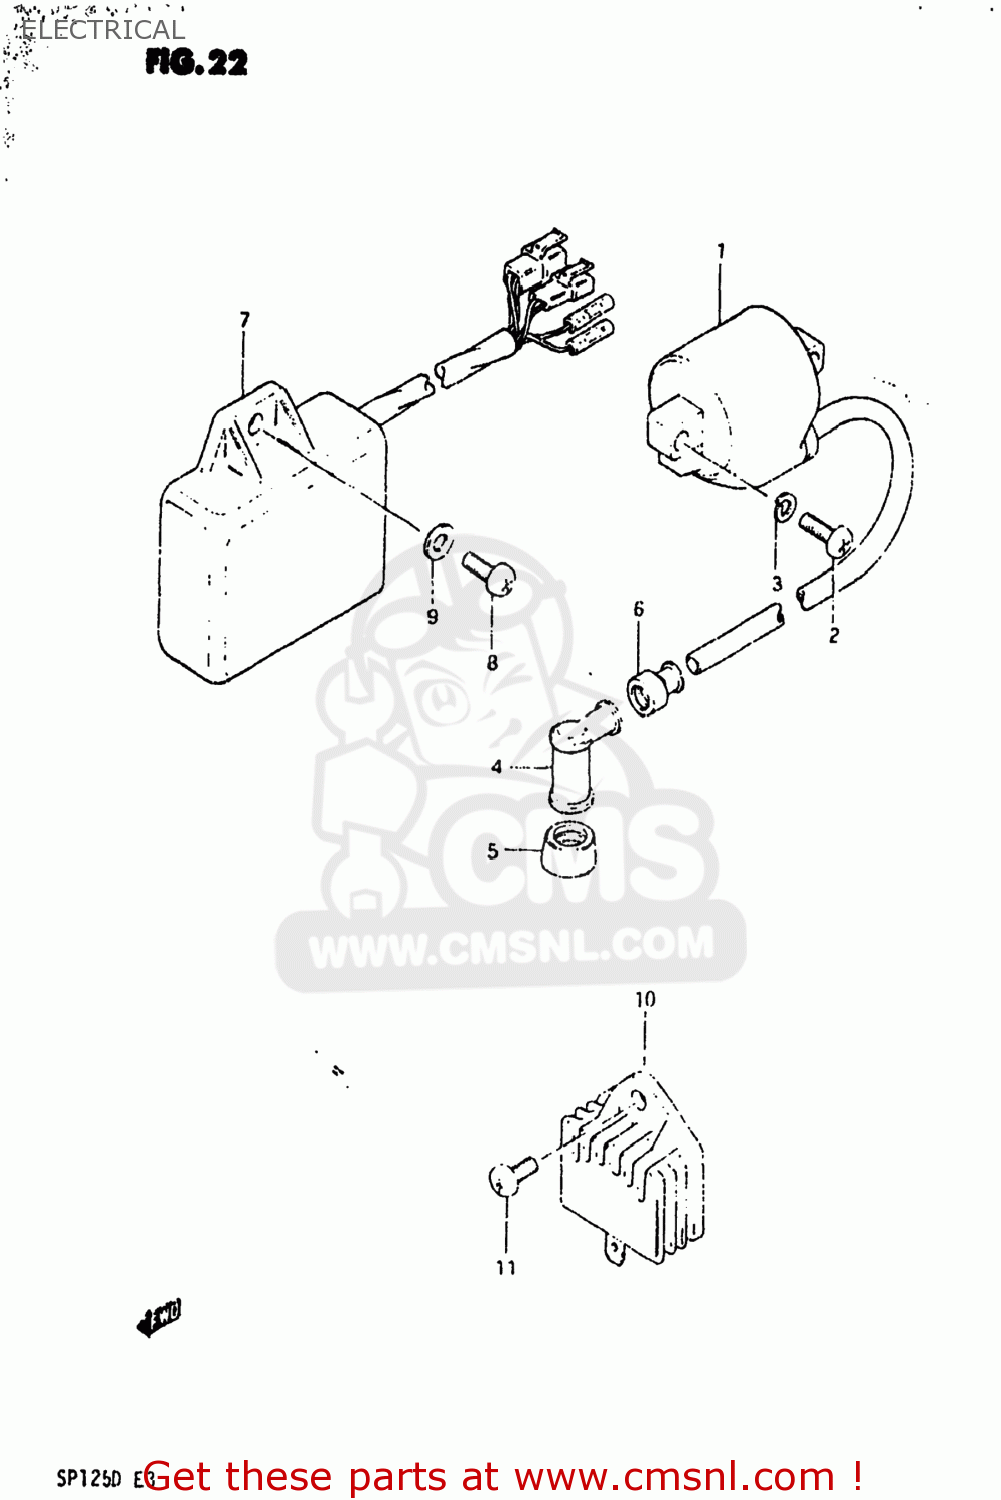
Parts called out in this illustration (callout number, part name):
1	COIL ASSEMBLY,IGNITION
2	SCREW
3	LOCK WASHER
4	CAP ASSY,SPARK PLUG
5	SEAL,SPARK PLUG
6	SEAL,SPARK PLU
7	CDI UNIT
8	SCREW
9	WASHER
10	RECTIFIER ASSY,REGULATOR
11	SCREW 6X12
